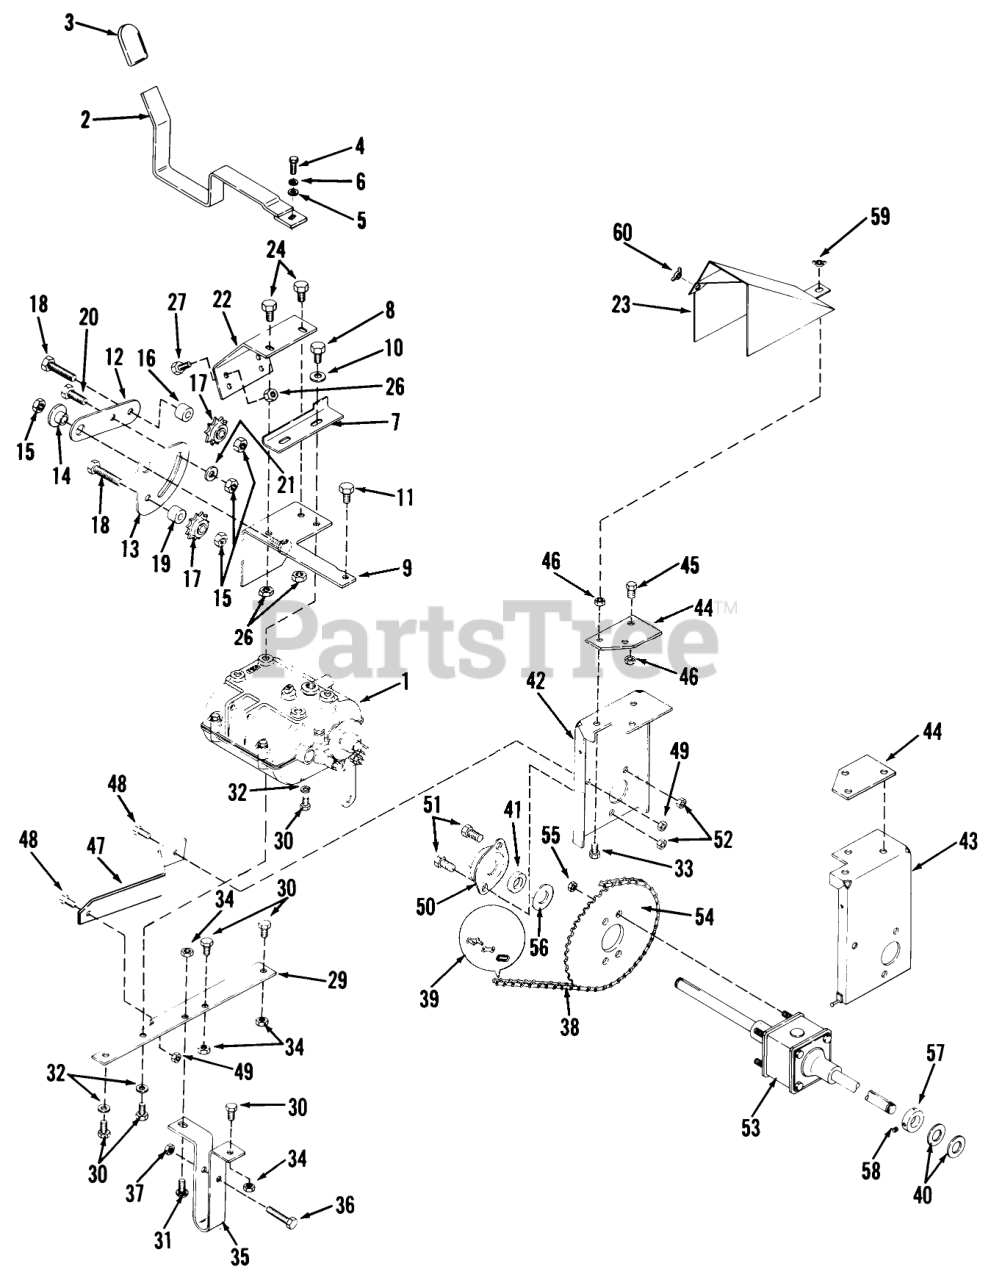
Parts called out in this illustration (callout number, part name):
1	SEE SEVICE BULT #228
5	WASHER
10	WASHER 5/16 SAE
11	Screw
14	SPACER-BUSHING
19	SPACER
40	WASHER
54	SPROCKET
56	WASHER
